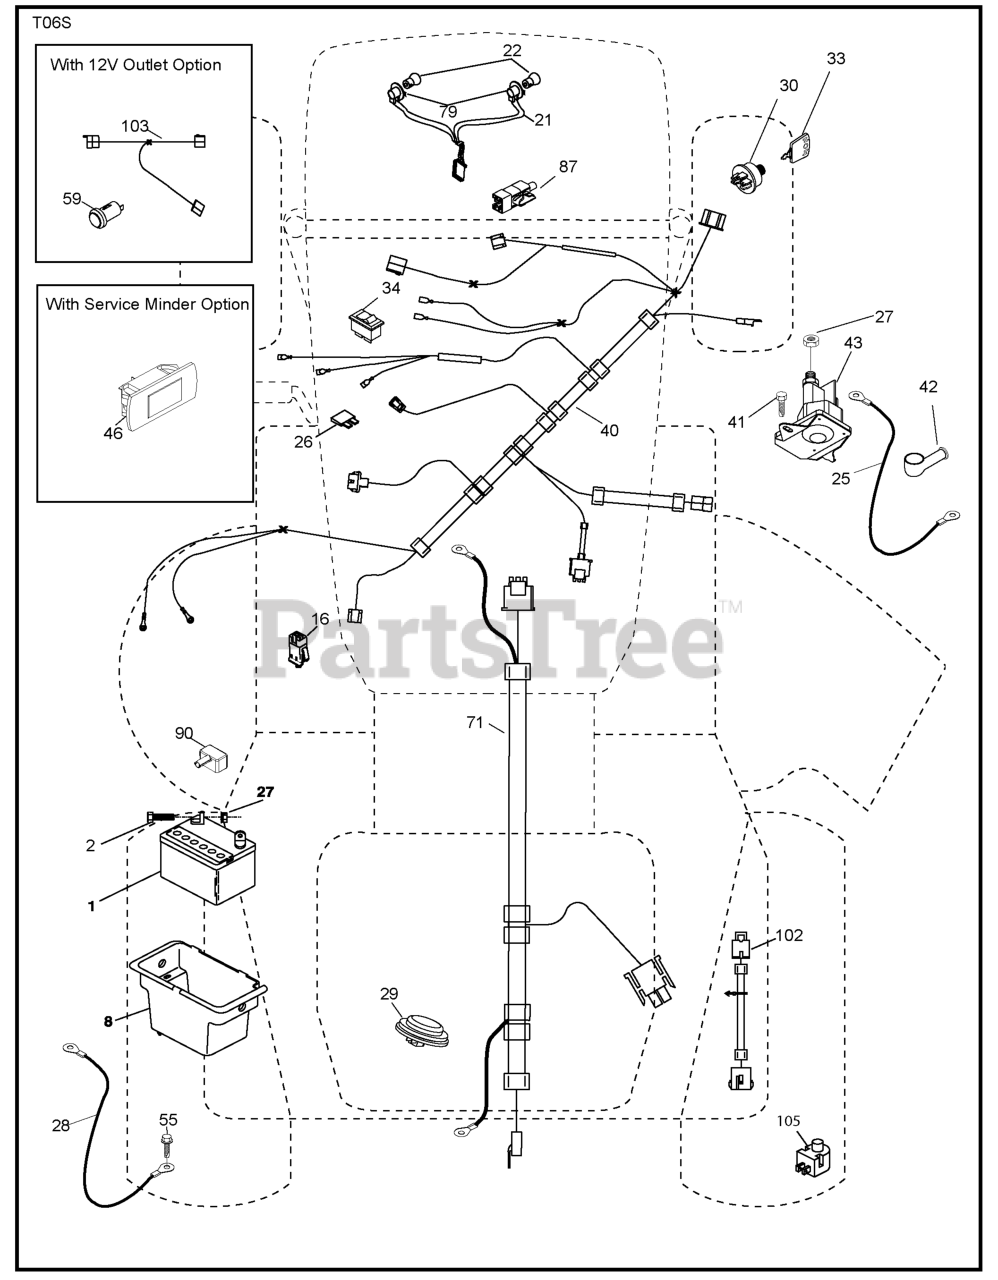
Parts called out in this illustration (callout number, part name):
1	Battery
2	BOLT.HEX.1/4.X.3/4.DICHROMATE
8	BOX.BATTERY.MNT.REAR.L
16	SWITCH INTERLOOK PUSH-IN
21	HARNESS.LIGHT W/4152J BULBS
25	CABLE.STARTER.6G.BL/RED.17.5
26	FUSE 20AMP
27	NUT
28	CABLE.BLACK.18"REAR.BA
29	SWITCH.SEAT.DELTA.OPC.
30	SWITCH.IGN.DELTA.W.LGH.ROS
33	KEY.CHAIN.BLISTER.PACK.GEN.INT
40	HARNESS.IGN.CHASS.TEX.REAR.BAT
41	SCREW
42	TERMINAL COVER
43	SOLENOID.W/BRASS.PLUNGER
46	RP.GUAGE.SRVCMNDR.HRMTR.
55	SCREW 5/16"
71	HARNESS IGN. DASH
79	BULB HOLDER ASM.
87	SWITCH.INTRLCK.CLUTCH.
90	COVER, TERMINAL BATTERY
102	HARNESS PIGTAIL PCH TEX ROS
105	REVERSE SWITCH
